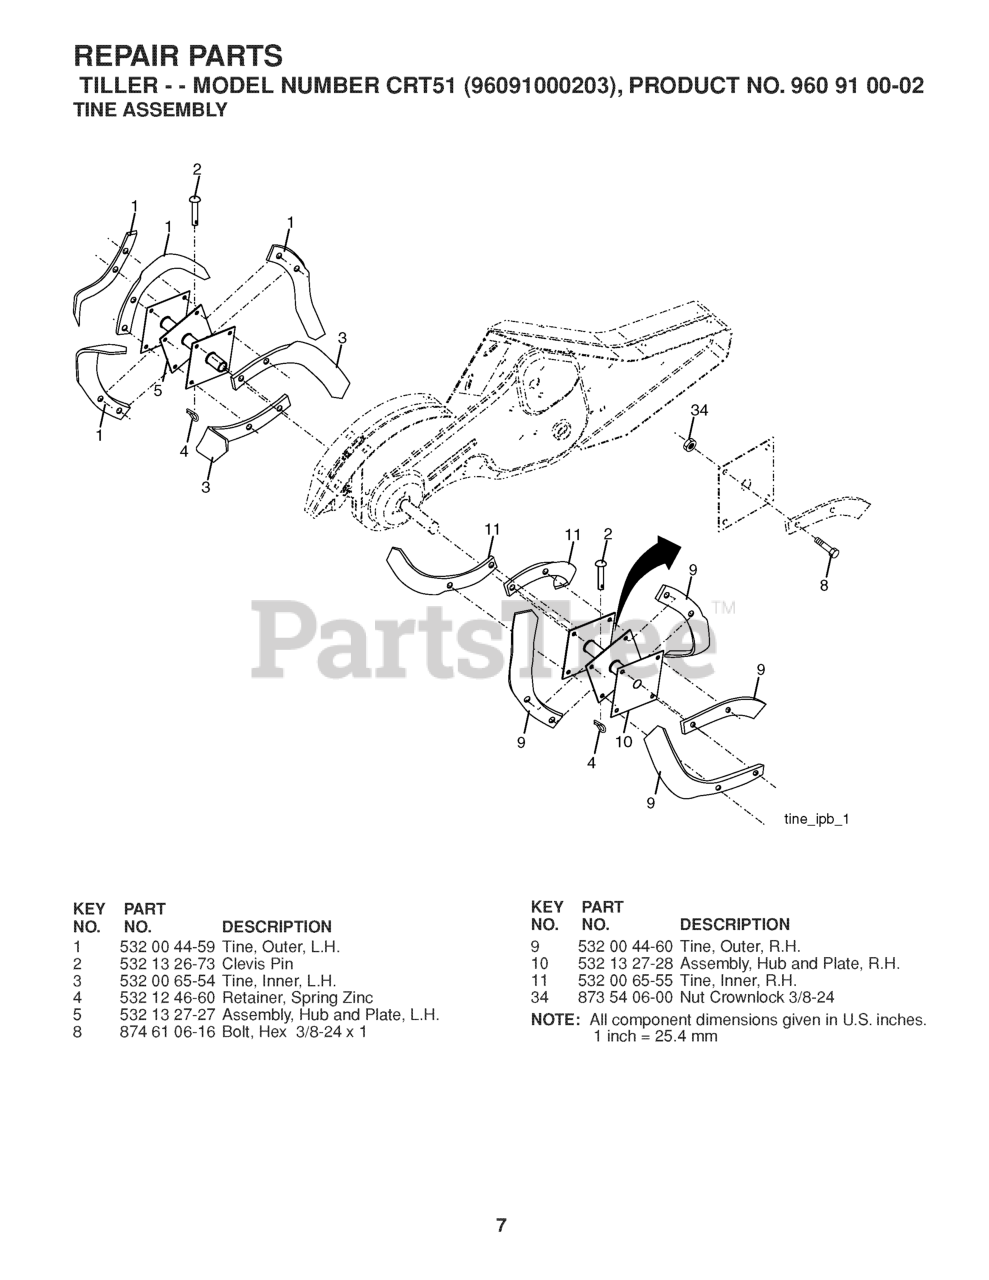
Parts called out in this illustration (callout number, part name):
1	TINE TI
2	PIN RETAINING SCREW
3	TINE.LH.12"(72L)
4	SPRING RETAINER
5	HUB.&.PLATE.ASM.LH
8	BOLT.HEX.001X20.37-24X1.ZINC
9	TINE TI
10	HUB & PLATE ASM RH
11	TINE.RH.12"(72R)
34	NUT CROWNLOCK 3/8-24
